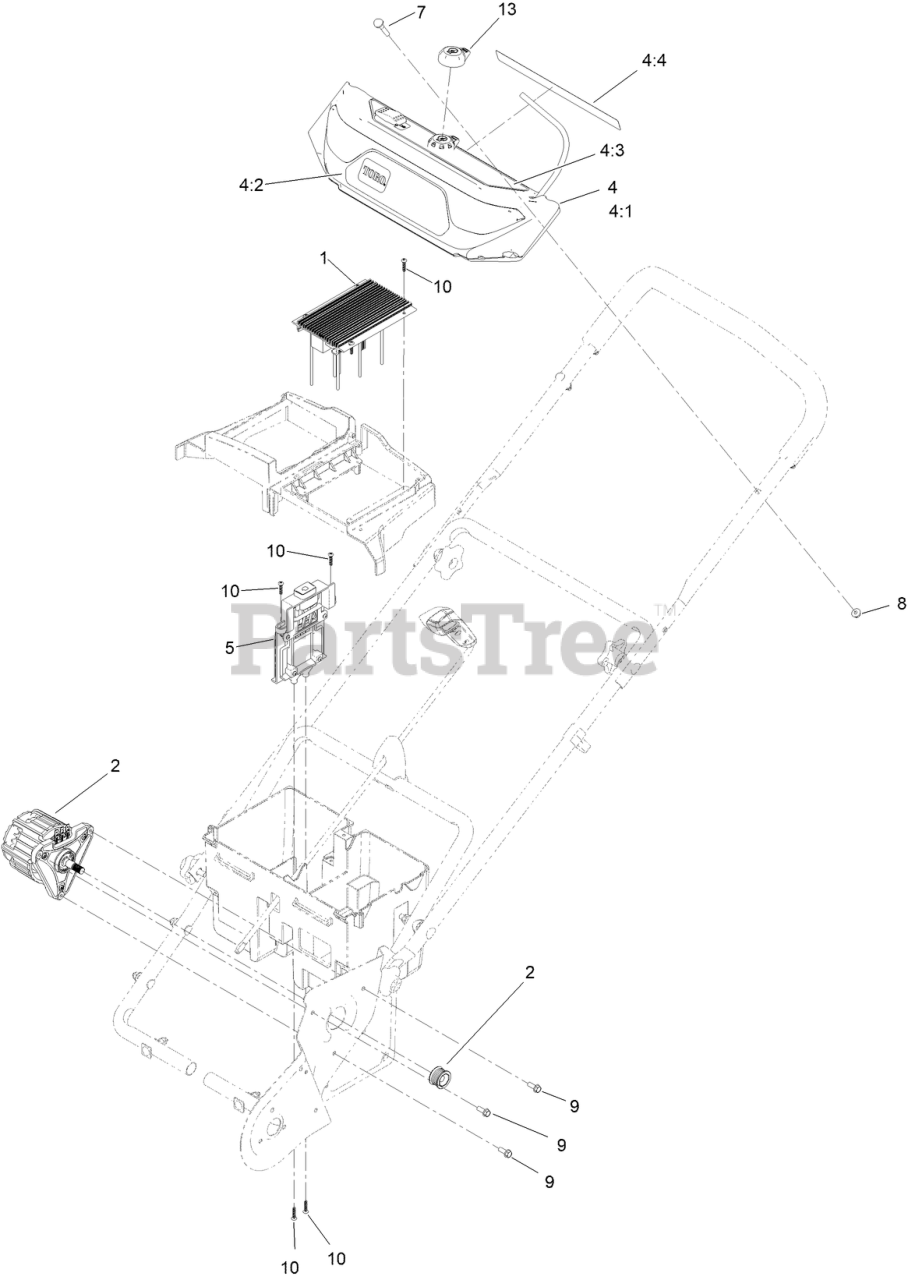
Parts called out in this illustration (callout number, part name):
1	MOTOR-DRIVER, SNOW (60V)
2	MOTOR-60V
4	DASH PANEL ASM W/DECALS
4:1	DASH PANEL ASM
4:2	DECAL-POWER CLEAR
4:3	DECAL-OPERATION
4:4	DECAL-CAUTION
5	BATTERY TRACK ASSEMBLY
7	SCREW-HANDLE
8	NUT-FLANGE, NI
9	SCREW-HWH
10	SCREW-PPH
13	KEY-BAIL
